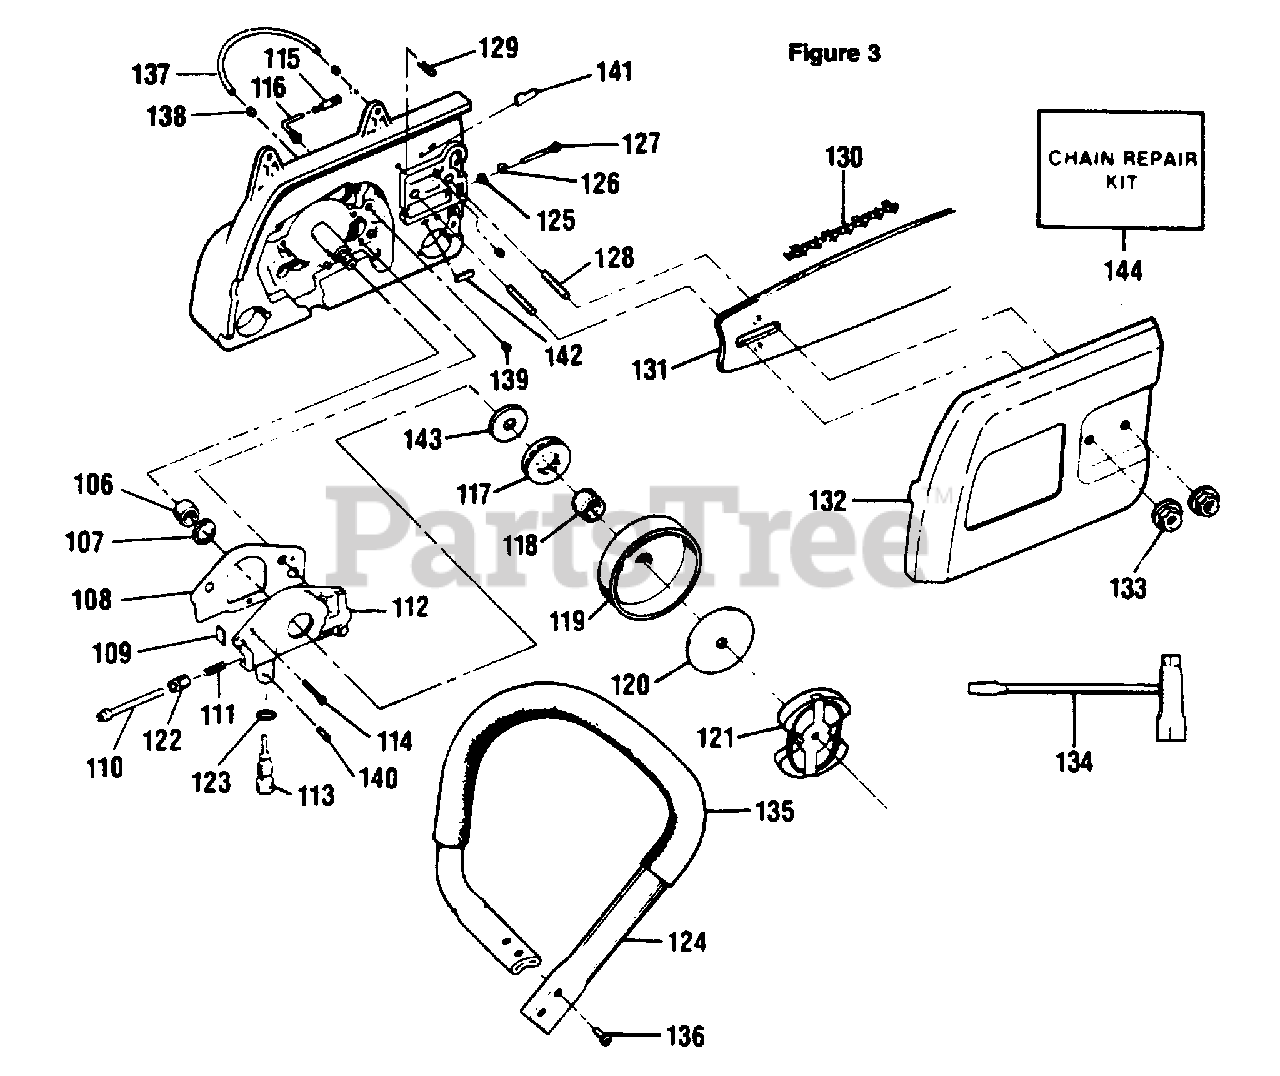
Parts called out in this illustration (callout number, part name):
106	Worm Gear
108	Gasket Set
109	Dust Plug
112	Oil Pump Kit (Inc. 106,107,109,110,111,113, 122,123,140)
113	Screw Oiler Adjustment
115	Oil Pickup & Filter
116	Oiler Intake Line
117	Rim Sprocket (3000 CB only)
118	Clutch Bearing
119	Drum Sprocket Model 3000 CB
120	Clutch Plate
121	Clutch Ass'y
122	Oiler Gear Spur
123	"O" Ring
124	Handlebar Ass'y.Model 3000 CB
125	Bar Adjusting Pin
126	"E" Ring
127	Screw
128	Bar Stud
129	Vent Pin
130	Chain 16" (34 LG-64)
131	Bar 16" Model 3000 CB
132	Bar Clamp Ass'y. (Inc. #142)
133	Nut
135	Handlebar Grip
137	Oiler Discharge Line
138	Oiler Discharge Sleeve
139	Tubing Nut
140	Oiler Adjustment Pin
141	Chain Pad - Top
142	Chain Pad
143	Thrust Washer
144	Chain Repair Kit
